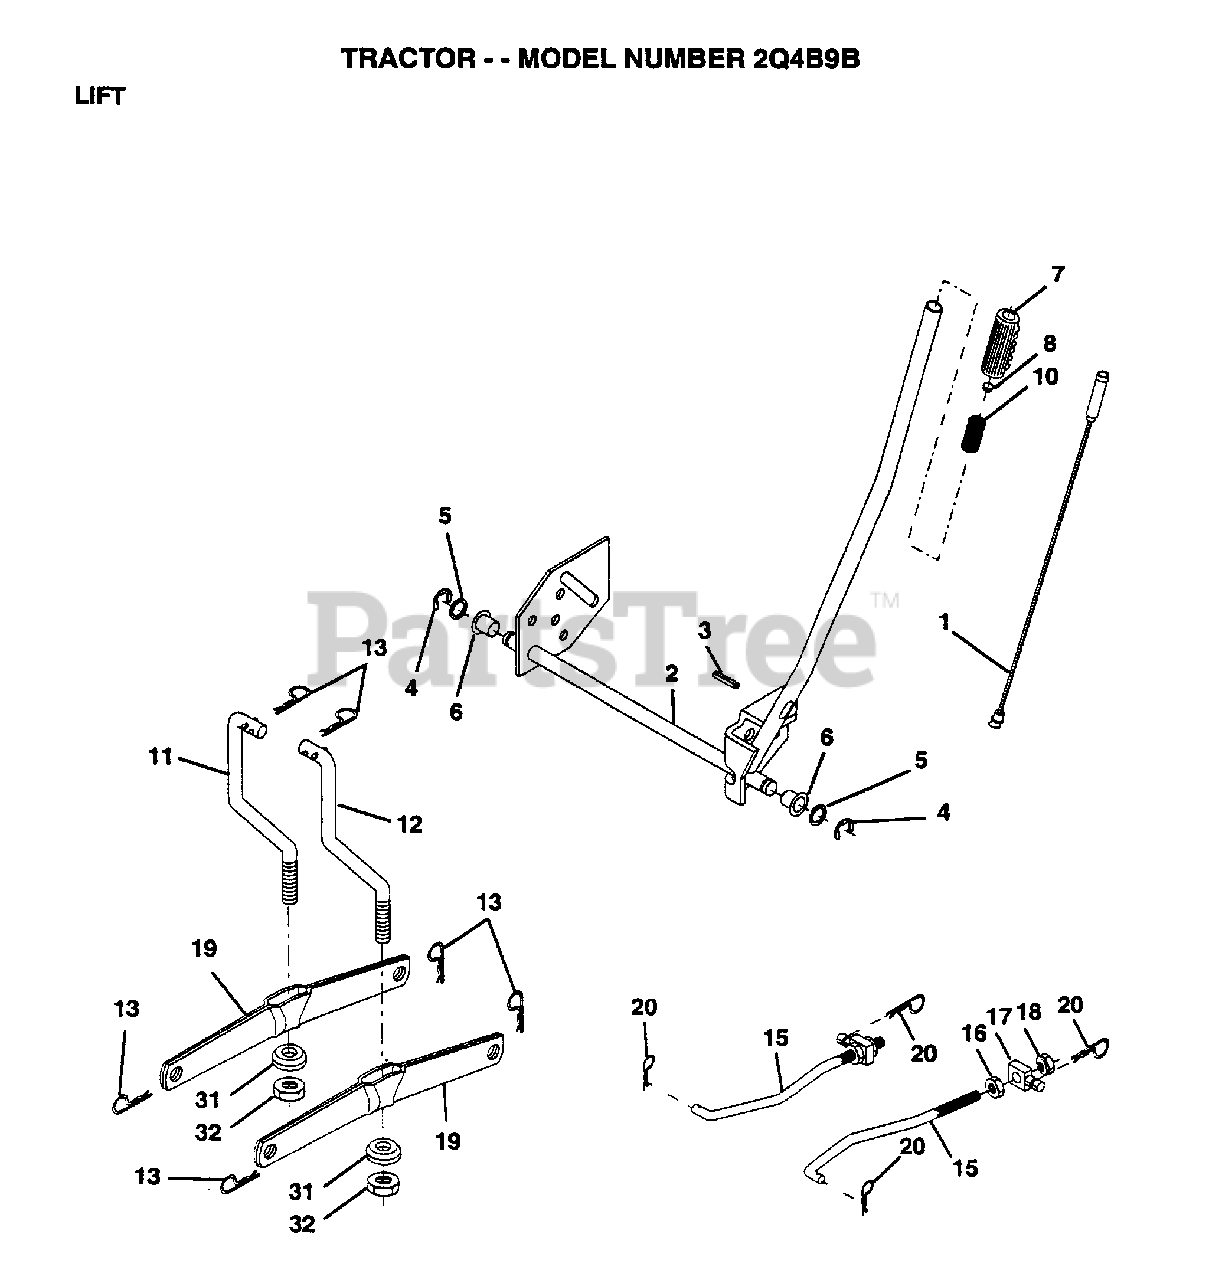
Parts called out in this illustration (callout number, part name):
1	WIRE ASM
3	PIN-GROOVE LT
5	WASHER
6	NYLON BEARING
7	GRIP
15	LINK.FRONT
16	NUT
17	TRUNION
18	NUT.LK.W/WSH.1/2.
19	ARM SUSP REAR
20	RETAINER.SPRING
31	BEARING PVT LH
32	NUT.CROWNLOCK.3/8
